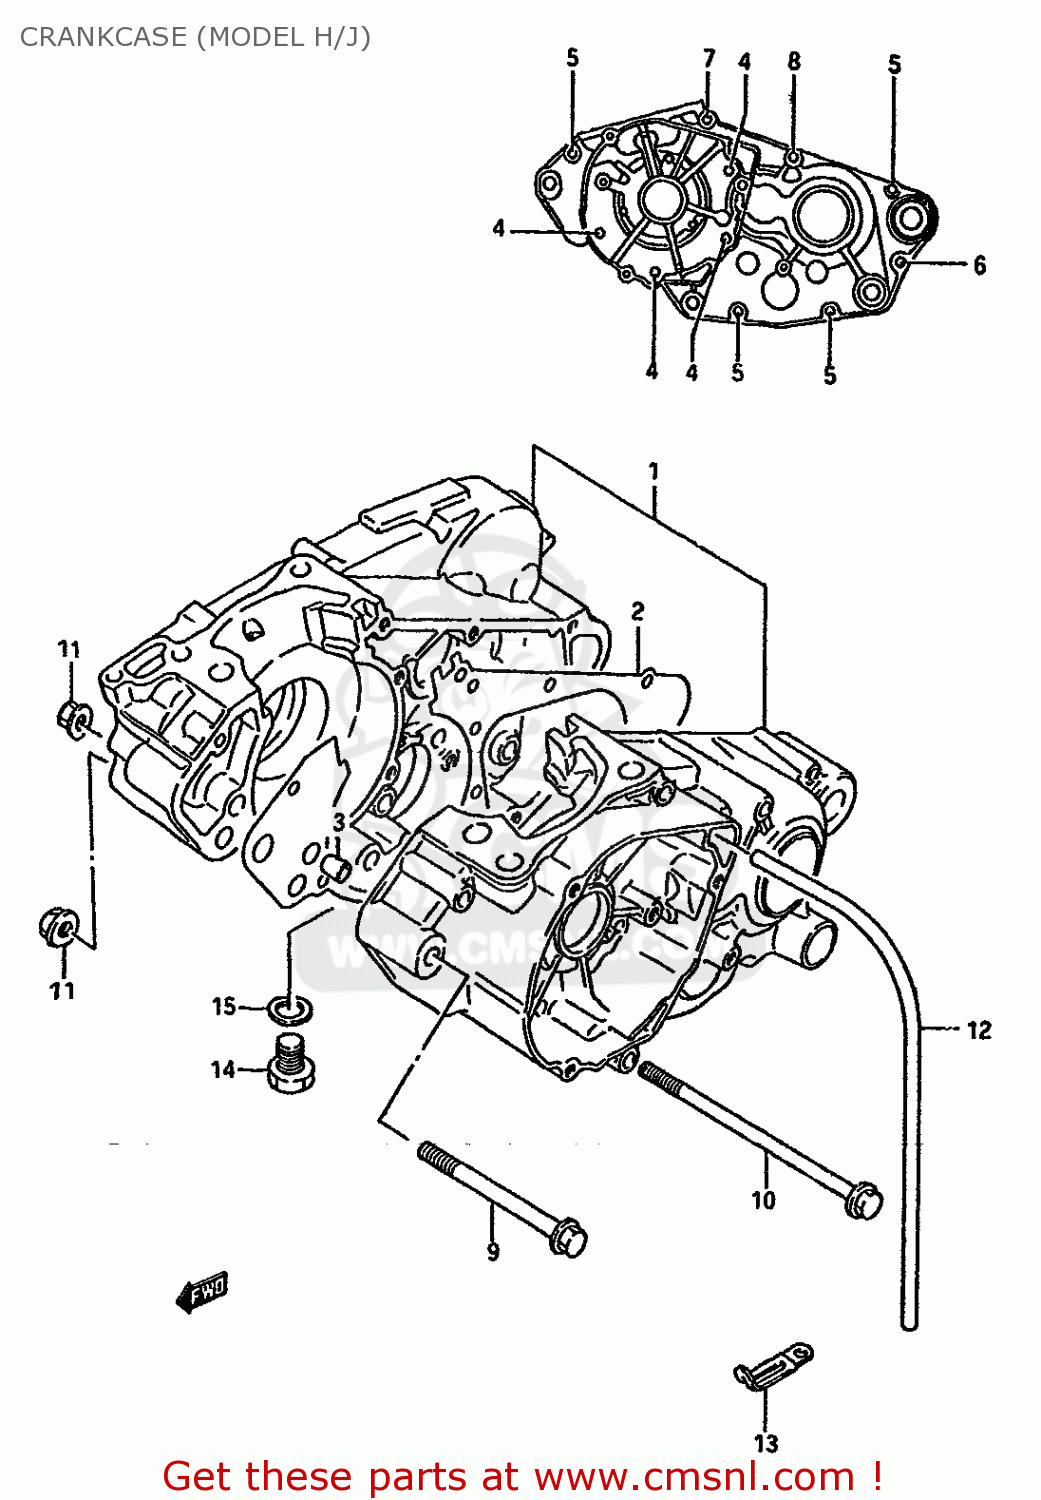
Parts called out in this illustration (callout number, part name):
1	CRANKCASE SET
2	GASKET,CRANKCASE (MCA)
3	PIN
4	SCREW
5	SCREW
6	SCREW 6X60
7	SCREW 6X70
8	SCREW 6X80
9	BOLT(8X95)
10	BOLT(8X150)
11	NUT
12	HOSE
13	CLAMP
14	PLUG
15	GASKET(14X19.2X2) (NAS)
